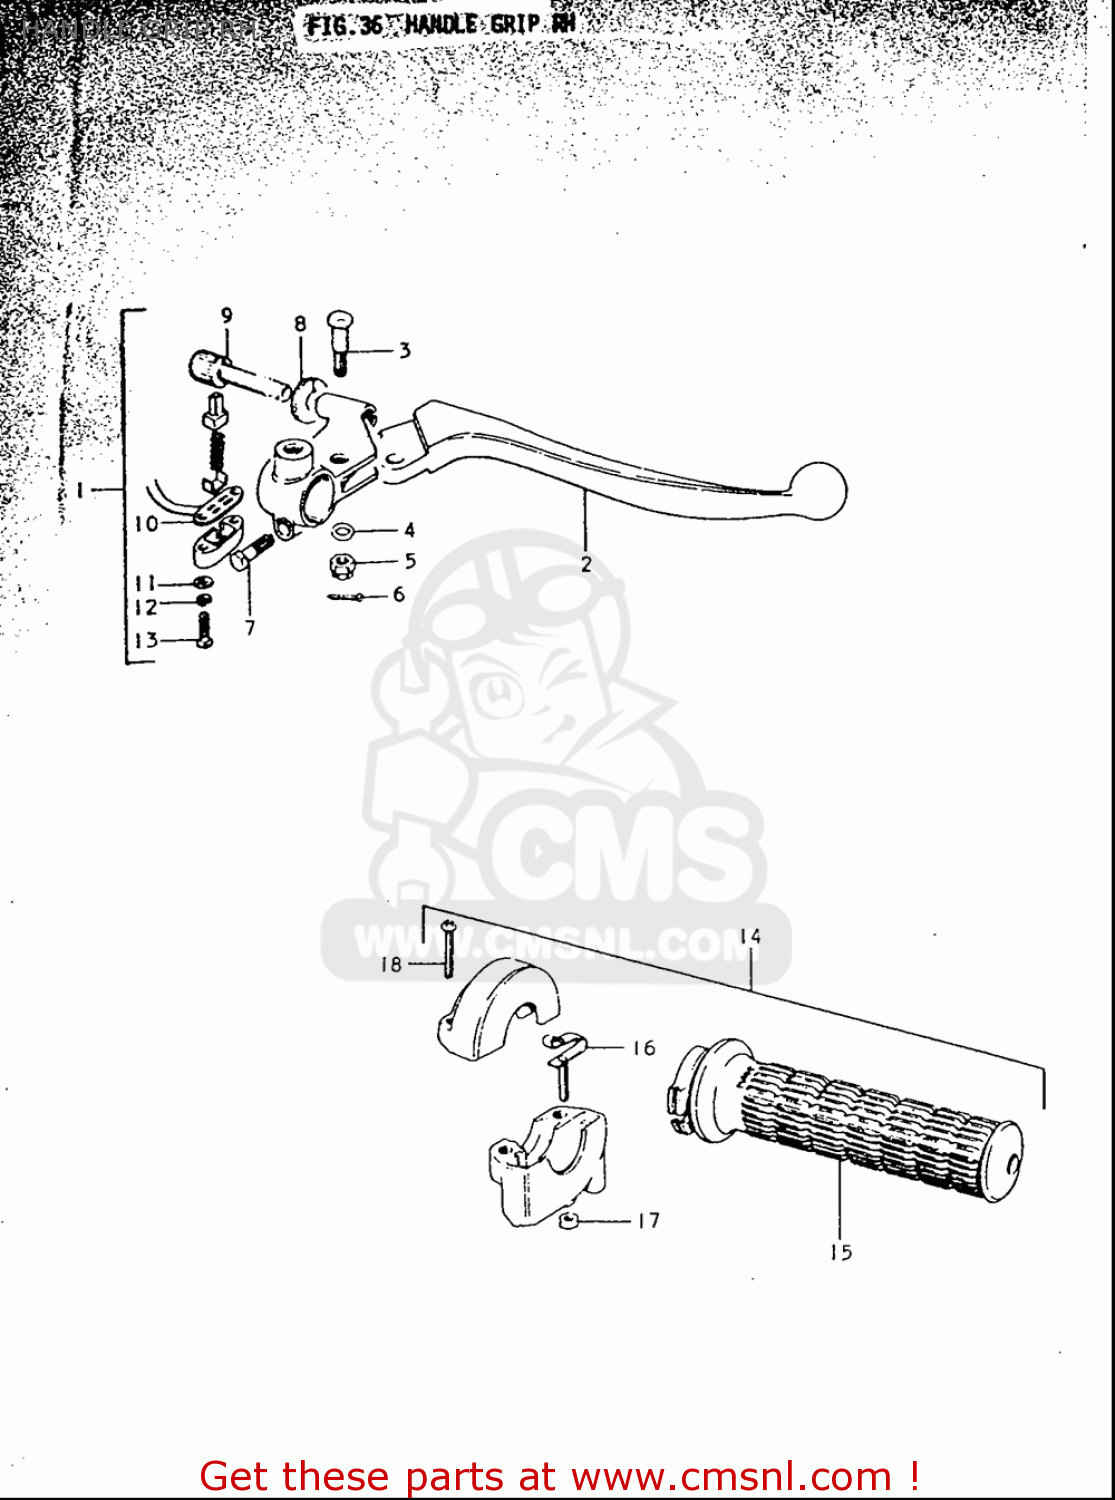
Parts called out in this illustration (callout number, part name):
3	BOLT,LEVER PIVOT
4	WASHER,LOCK
5	NUT,LEVER FITTNG
6	PIN 16X20
7	BOLT
8	NUT,CABLE ADJUSTER
9	ADJUSTER,CABLE
11	WASHER
12	WASHER,LOCK
13	SCREW
15	GRIP,THROTTLE
16	ADJUSTER, THROTTLE
17	NUT
